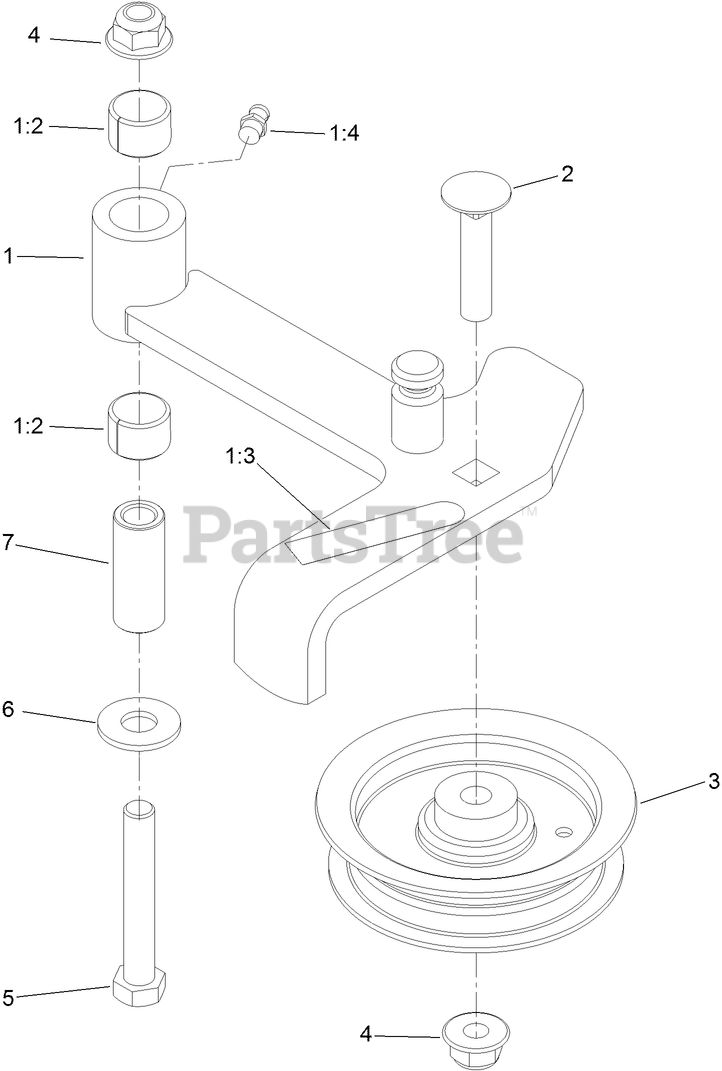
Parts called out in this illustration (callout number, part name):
1	IDLER ARM WITH BUSHING ASM
1:2	BUSHING
1:3	DECAL-WARNING
1:4	FITTING-GREASE
2	SCREW-CARR
3	IDLER-FLAT
4	NUT-HF, NI
5	SCREW-HH
6	WASHER-FLAT
7	BUSHING
